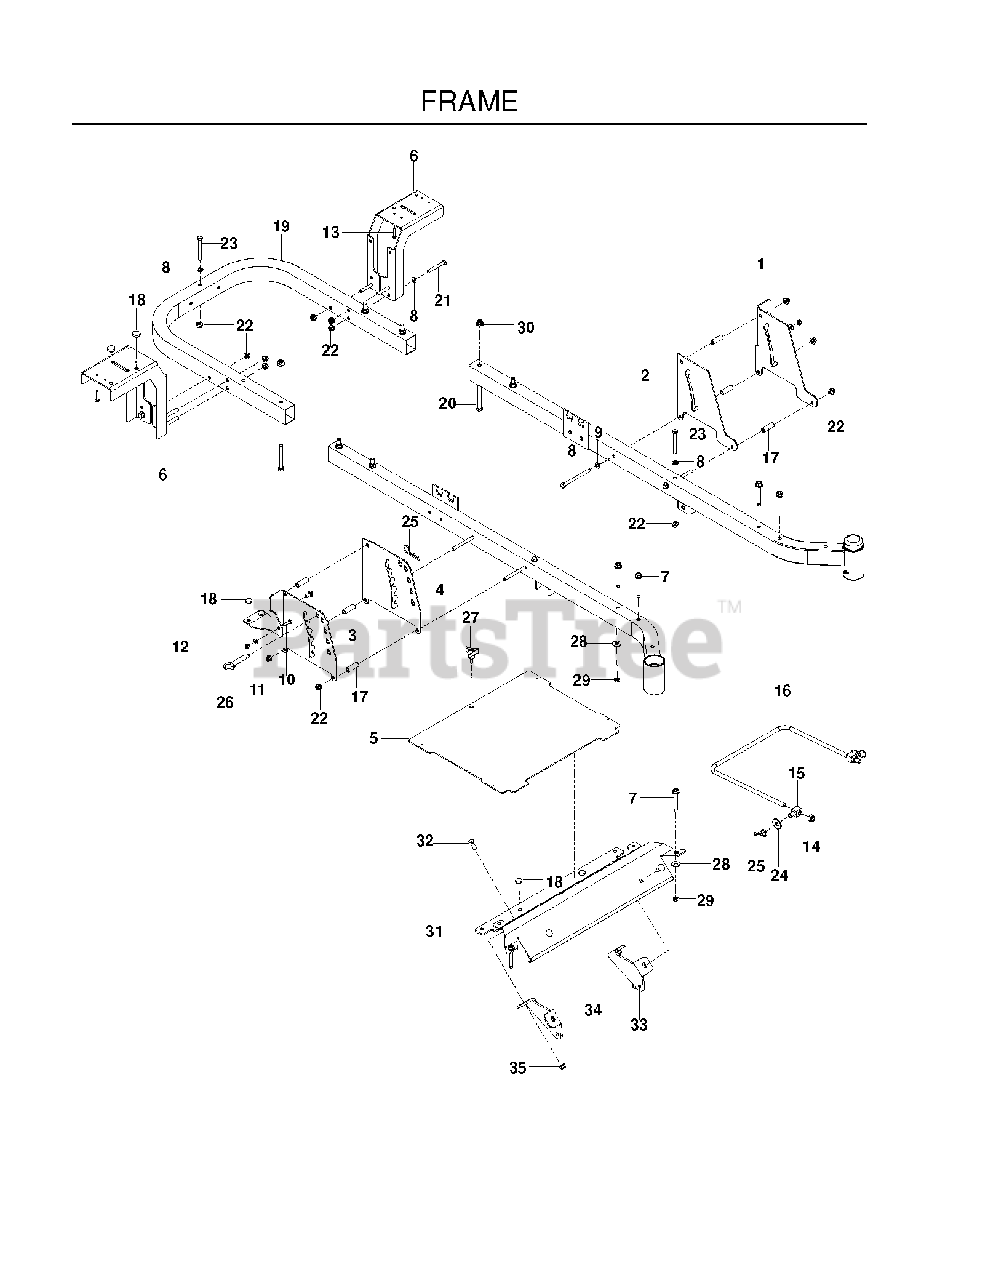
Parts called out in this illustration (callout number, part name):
1	PLATE, OUTER BRAKE, BLACK
2	PLATE, BRAKE LATCH, BLACK
3	PLATE, DECK HEIGHT, BLK EZ
4	PLATE, DECK HEIGHT, BLACK
5	PLATE, FOOT, YLW
6	SUPPORT, FENDER, BLACK
7	ENGINE BOLT, SPECIAL
8	FLAT WASHER 5/16 SAE
9	HCS 5/16C X 4
10	HCS 1/4C X 1
11	WASHER 1/4 SAE
12	NUT 1/4-20 NYLOC
13	SCR #10-12X1-1/2HEX WASH HD ZD
14	7/16-14 HEX NUT W/NYL RING ZD
16	LINK, FRONT SUSP.
17	SPACER, .334 ID X .5 OD X 1.5
18	GROMMET, BUMPER
19	FRAME TUBE, REAR, YLW
20	HCS 3/8C X 3
21	CAPSCREW
22	5/16-18 NYLOC FLANGE NUT
23	HCS 5/16C X 2-3/4
24	WASH USS FLAT 1/2
25	HAIRPIN #4
26	HITCH PIN
27	KNOB W/STUD
28	WASHER 3/8 FLAT
29	NUT HEX 3/8-16 NYLON, THIN
30	NUT 3/8-16 HEX FLG NYLOC ZD
31	FOOT, REST, MED YLW
32	RHSNB 3/8C X 1
33	MOUNT, STRUT, RT, BLK
34	MOUNT, STRUT, LT, BLK
